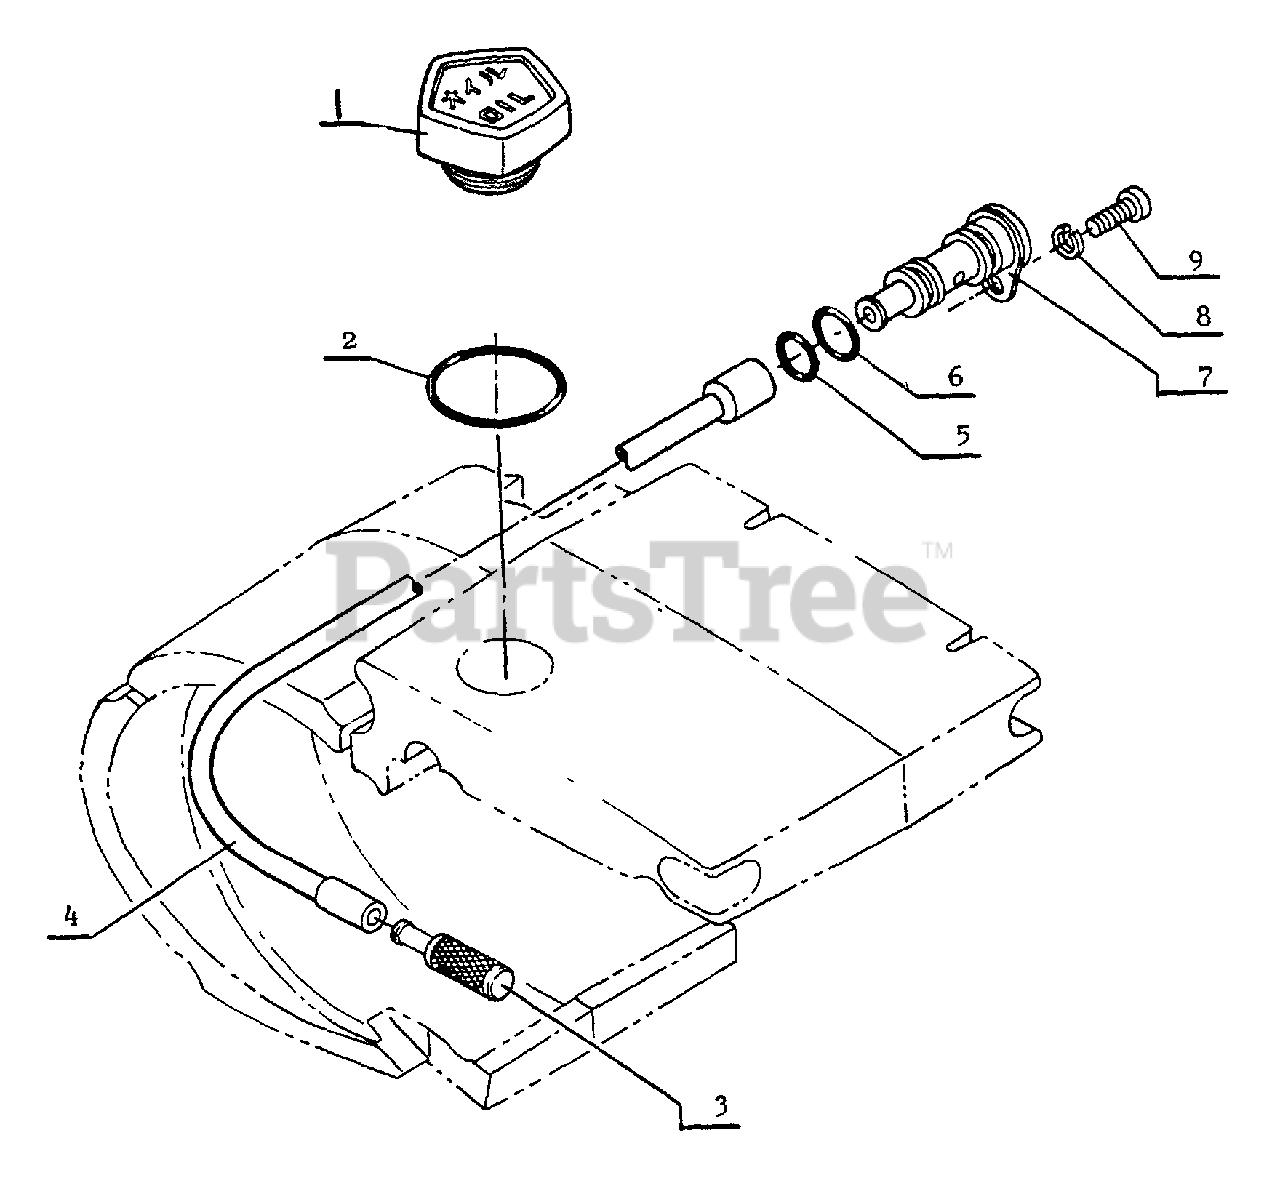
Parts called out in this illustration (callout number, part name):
1	CAP ASSY
2	O-RING 18
3	FILTER, OIL
4	PIPE, OIL - INNER
5	O-RING 8 MM
6	O-RING 9 MM
7	CONNECTOR, PIPE
8	WASHER, SPRING 4 MM
9	SCREW 4×8
